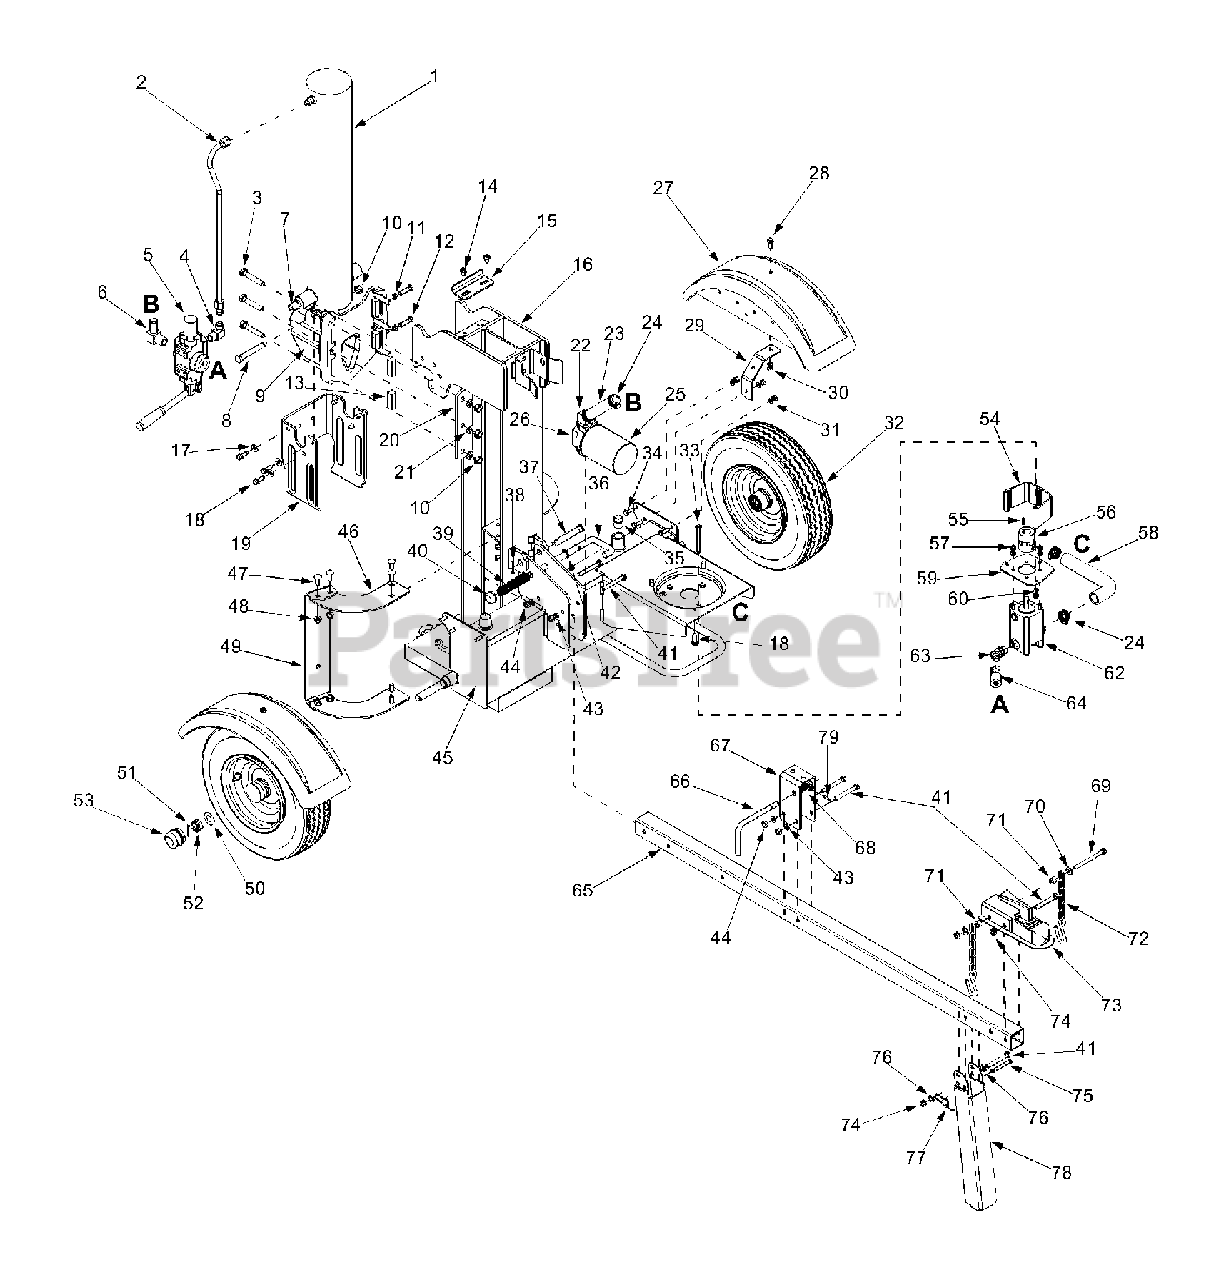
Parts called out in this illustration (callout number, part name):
1	Hydraulic Cylinder
1	Seal Kit 4.5" for Fisher Cylinder 718-0769
1	Kit Seal 4.5" for XINGHUI cylinder 718-0769A
1	Kit Seal 4.5" for ENERGY cylinder 718-0769A
2	Hydraulic Tube
3	Hex Cap Screw 1/2-20 x 2.75
4	90 Degree Solid Adapter
6	Return Elbow
7	Nipple Pipe 1/2-14
8	Hex Cap Screw 1/2-20 x 3.50
9	Wedge Assembly
10	Lock Nut 1/2-20
11	Hex Jam Nut 3/8-24
12	Hex Cap Screw 3/8-24 x 1.5
14	Hex Washer Screw 5/16-18 x .625
17	Flat Washer .406 ID x .875 OD
18	Hex Washer Screw 3/8-16 x 1.0
21	Lock Washer 1/2
22	Adapter 3/4-14
23	Return Hose 3/4" ID x 44" Lg.
24	Hose Clamp 5/8"
25	Oil Filter
26	Filter Housing
27	Fender, Plastic Red
27	Fender, Plastic
28	Hex Washer Screw 5/16-18 x .875
30	Hex Nut 5/16-18
31	Lock Washer 5/16
32	Wheel Assembly
33	Hex Screw 5/16-24 x 3.25
34	Hex Cap Screw 5/16-18 x 1.0
35	Pipe Plug
36	Lock Rod
37	Clevis Pin
38	Cotter Pin
39	Compression Spring
40	Push Cap
41	Hex Bolt 3/8-16 x 3"
42	Flat Washer .635 ID x .93 OD
43	L-Washer 3/8"
44	Hex Nut 3/8-16
45	Frame Assembly
48	Flanged Lock Nut 3/8-16
50	Flat Washer .760 ID x .500 OD
51	Cotter Pin
52	Slotted Nut 3/4-16
53	Hub Cap
54	Coupling Shield
55	Square Key 3/16" x .75
56	Flexible Coupling
57	Hex Nut 5/16-24
60	Lock Washer 5/16" ID
62	Gear Pump (11gpm)
63	45 Degree Elbow
64	High Pressure Hydraulic Hose
66	Latch Rod
68	Spring Compression
69	Hex Cap Screw 3/8-16 x 4.25
70	Flat Washer .385 ID x .870 OD
71	Spacer .375 ID x .625 OD
72	Chain
73	Coupling Hitch
74	Hex Lock Nut 3/8-16
75	Clevis Pin
76	Flat Washer .375 ID x .738 OD
77	Spring Pin
